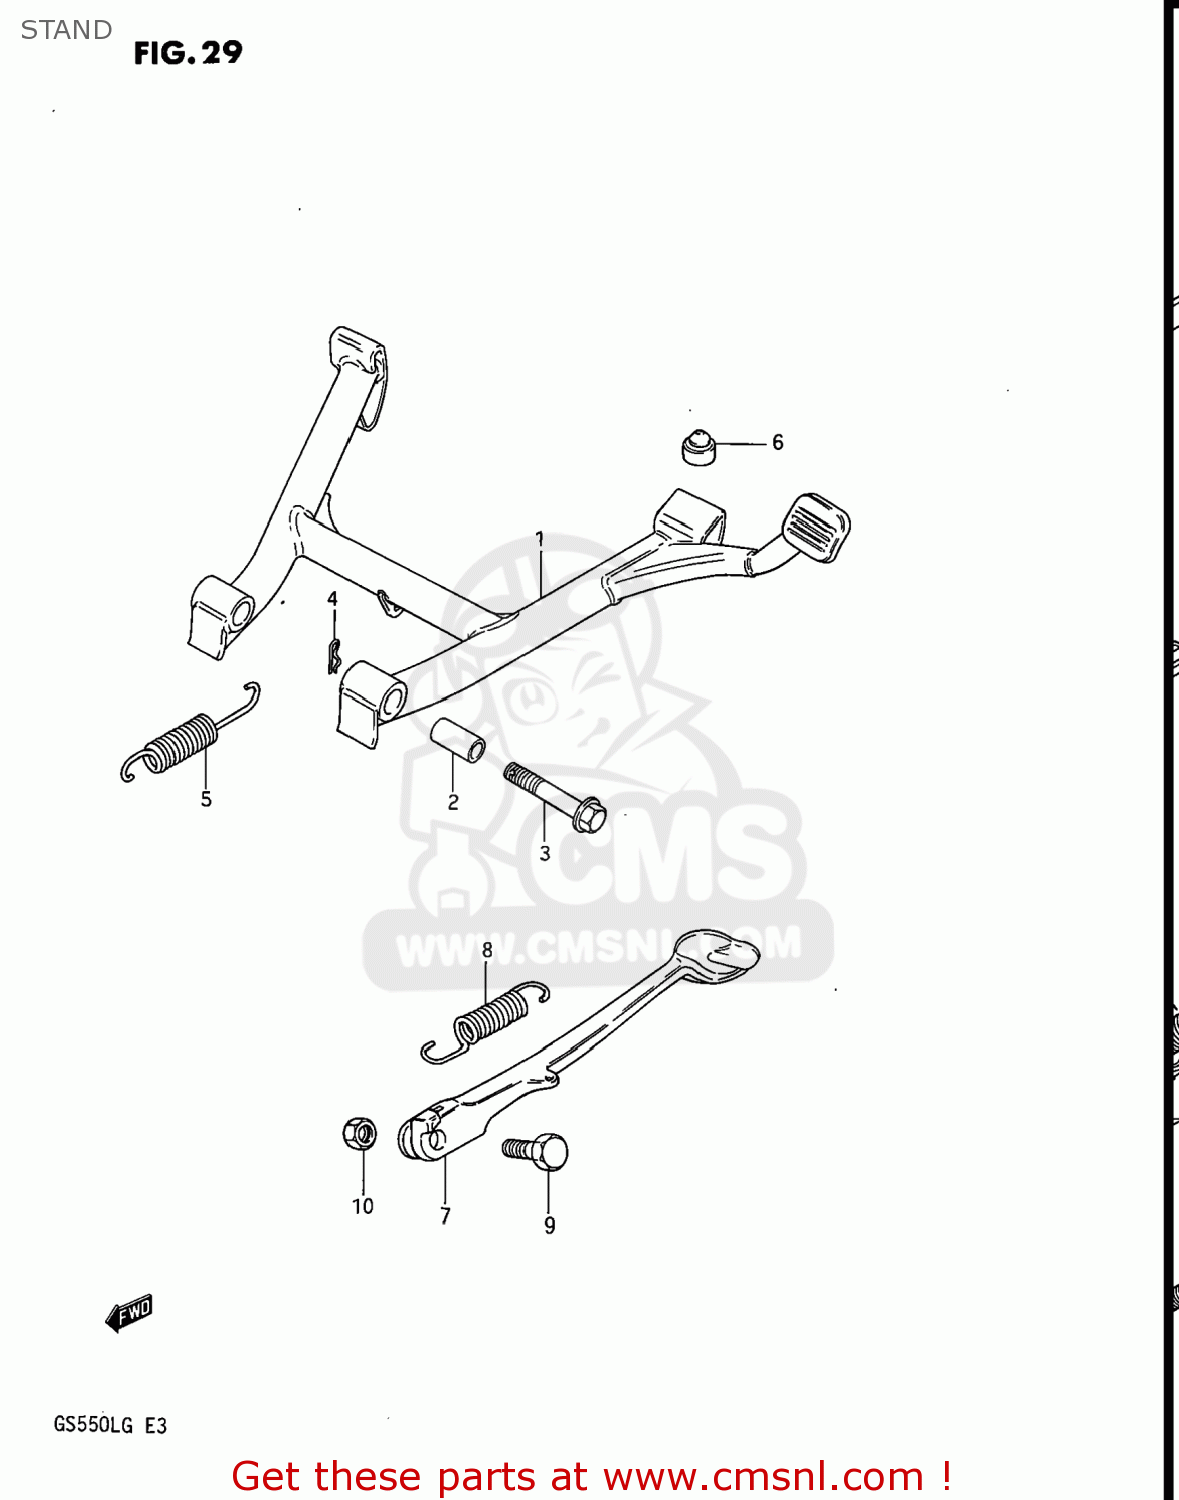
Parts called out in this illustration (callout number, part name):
1	STAND,CENTER
2	SPACER (10.5X16X31.8)
3	BOLT 10X50
4	CLIP
5	SPRING
6	CUSHION
7	STAND,SIDE
8	SPRING
9	BOLT L:30
10	NUTM10X1.25X8
